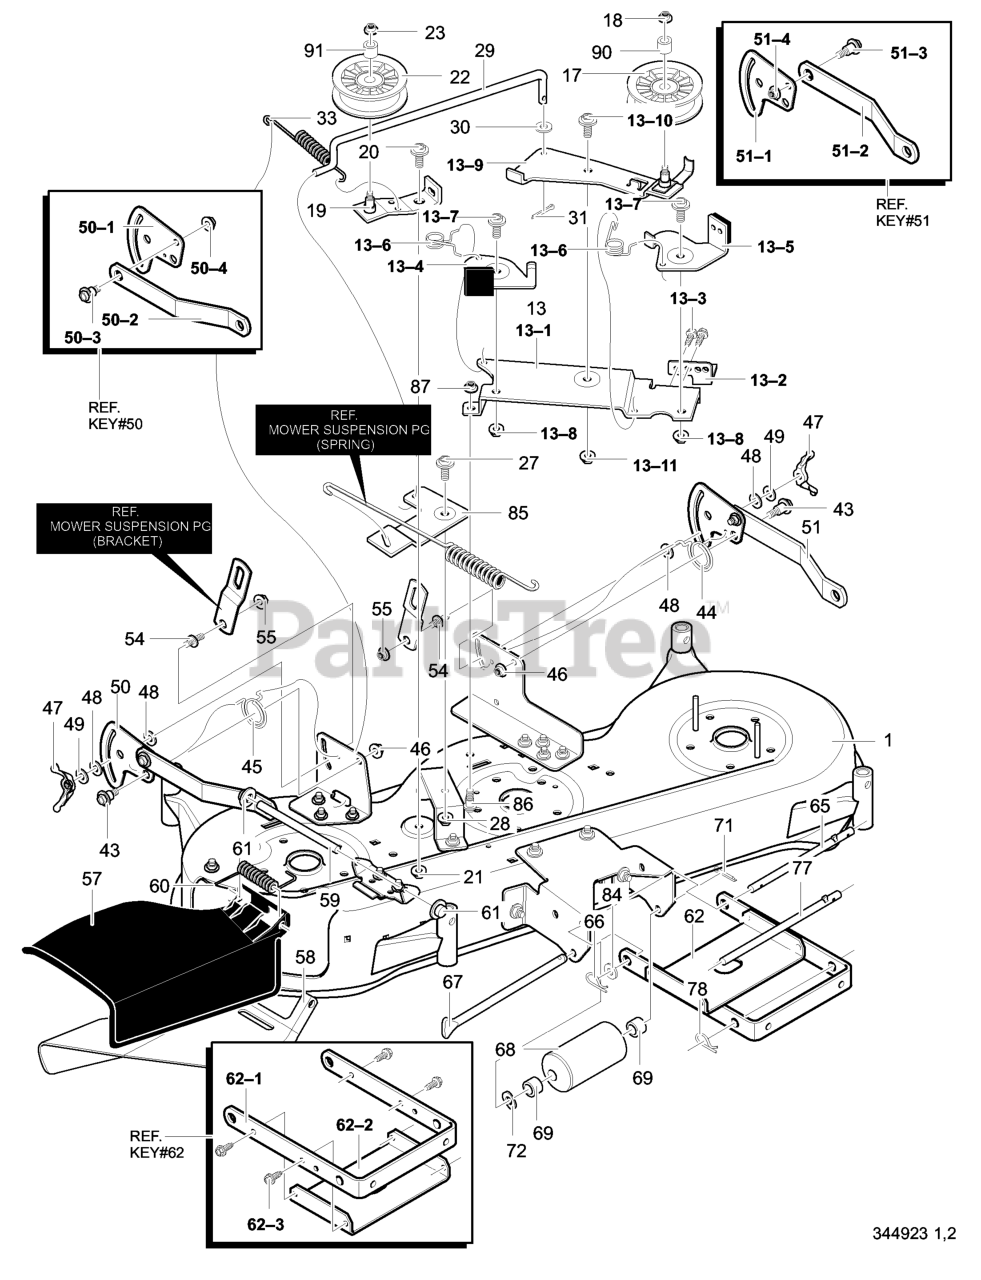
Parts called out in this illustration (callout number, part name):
1	46" MOWER DECK
13	BRACKET, MOUNTING
13-1	PLATE, BRAKE ARM
13-2	BRACKET, MOUNTING
13-4	ASSEMBLY, LEFT BRAKE
13-5	ASSEMBLY, BRAKE CENTER
13-6	TORSION SPRING
13-7	BOLT
13-8	LOCKNUT, FLANGE
13-9	ASSSEMBLY, IDLER ARM
13-10	BOLT
13-11	LOCKNUT, FLANGE
17	PULLEY, IDLER
18	NUT, 3/8-16
19	ASS'Y, RIGHT IDLER ARM
21	NUT 3/8-16
22	PULLEY, IDLER
23	NUT, 3/8-16
28	NUT, 3/8-16
29	LINK, BELLCRANK
30	WASHER, FLAT
31	PIN, COTTER
33	SPRING, EXTENSION
43	BOLT, SHOULDER
44	SPRING, TORSION
45	SPRING, TORSION
46	NUT, 3/8-16
47	WINGNUT, 5/16-18
48	PAD, FRICTION
49	WASHER
50	BRKT, RIGHT SUSPENSION
50-1	PLATE, SUSPENSION
50-2	BRKT, REAR SUSPENSION
50-3	BOLT, SHOULDER
50-4	LOCKNUT, FLANGE
51	BRKT, LEFT SUSPENSION
51-1	PLATE, SUSPENSION
51-2	BRKT, REAR SUSPENSION
51-3	BOLT, SHOULDER
51-4	LOCKNUT, FLANGE
54	PIN, HANGER
55	NUT, 3/8-16
57	DEFLECTOR, CHUTE
58	DEFLECTOR, INNER CHUTE
59	ROD, DEFLECTOR
60	SPRING, TORSION
61	NUT, PUSH CAP
62	BRACKET & STIFFENER
62-1	BRKT, FRONT SUSPENSION
62-2	STIFFENER
65	ROD, DECK
66	PIN, HAIR
67	ROD, ROLLER
71	PIN, COTTER
72	WASHER, WAVE
77	ROD, HANGER
78	PIN, HAIR
84	WASHER, FLAT
85	BELLCRANK
87	NUT, 5/16-18
90	SPACER 1/2 TO 17MM
91	SPACER 1/2 TO 17MM
